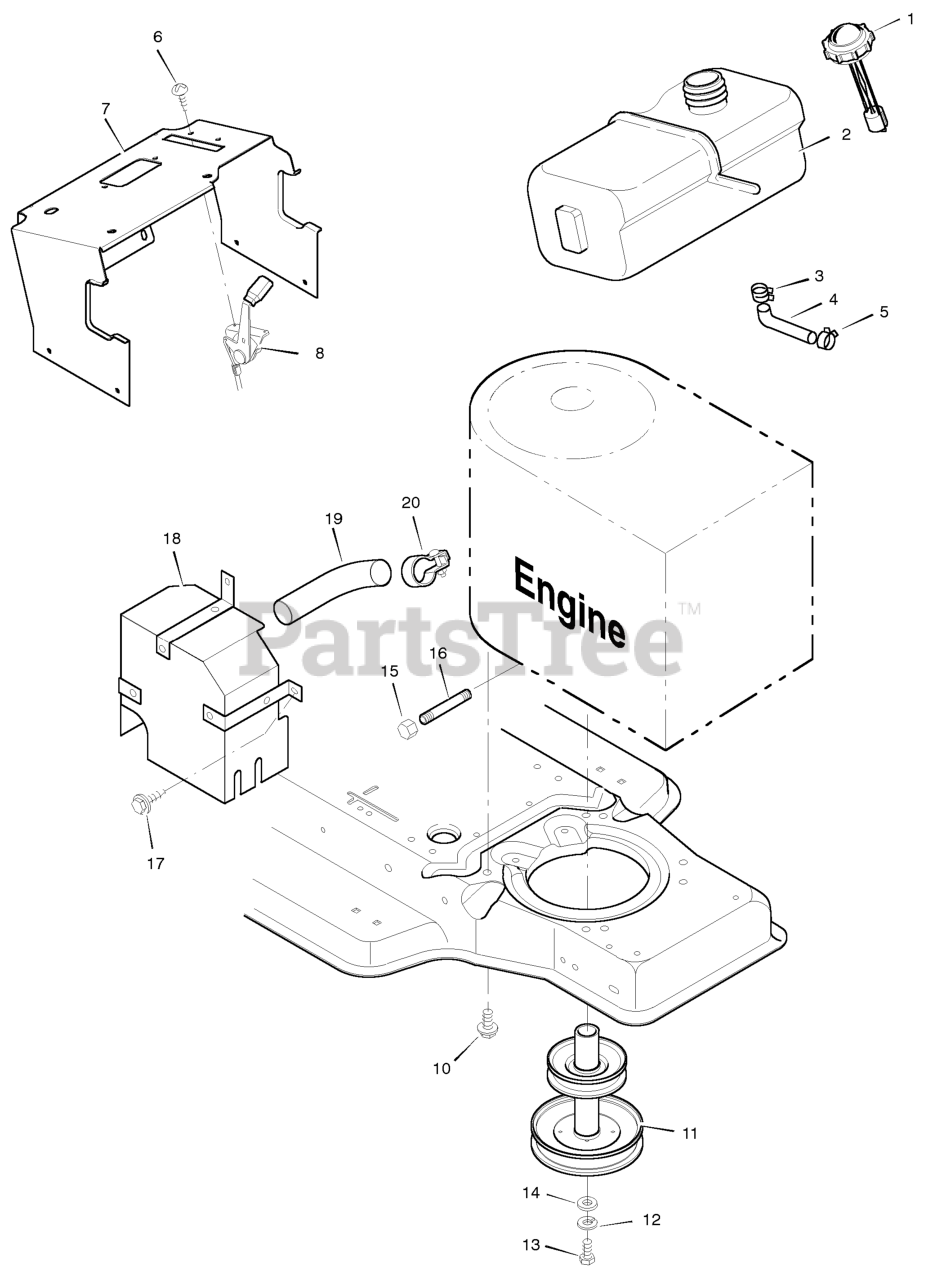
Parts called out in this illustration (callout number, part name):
1	Fuel Cap
2	Fuel Tank
3	Hose Clamp
4	Fuel Line
5	Hose Clamp
7	Support, Dash
8	Throttle Control
9	Engine *
10	Bolt, Engine Mount
11	Stack Pulley Assembly
12	Lockwasher
13	Bolt, Hex
15	Cap, Oil Drain
16	Pipe, Oil Drain
18	Shield, Heat
19	Pipe, Exhaust
